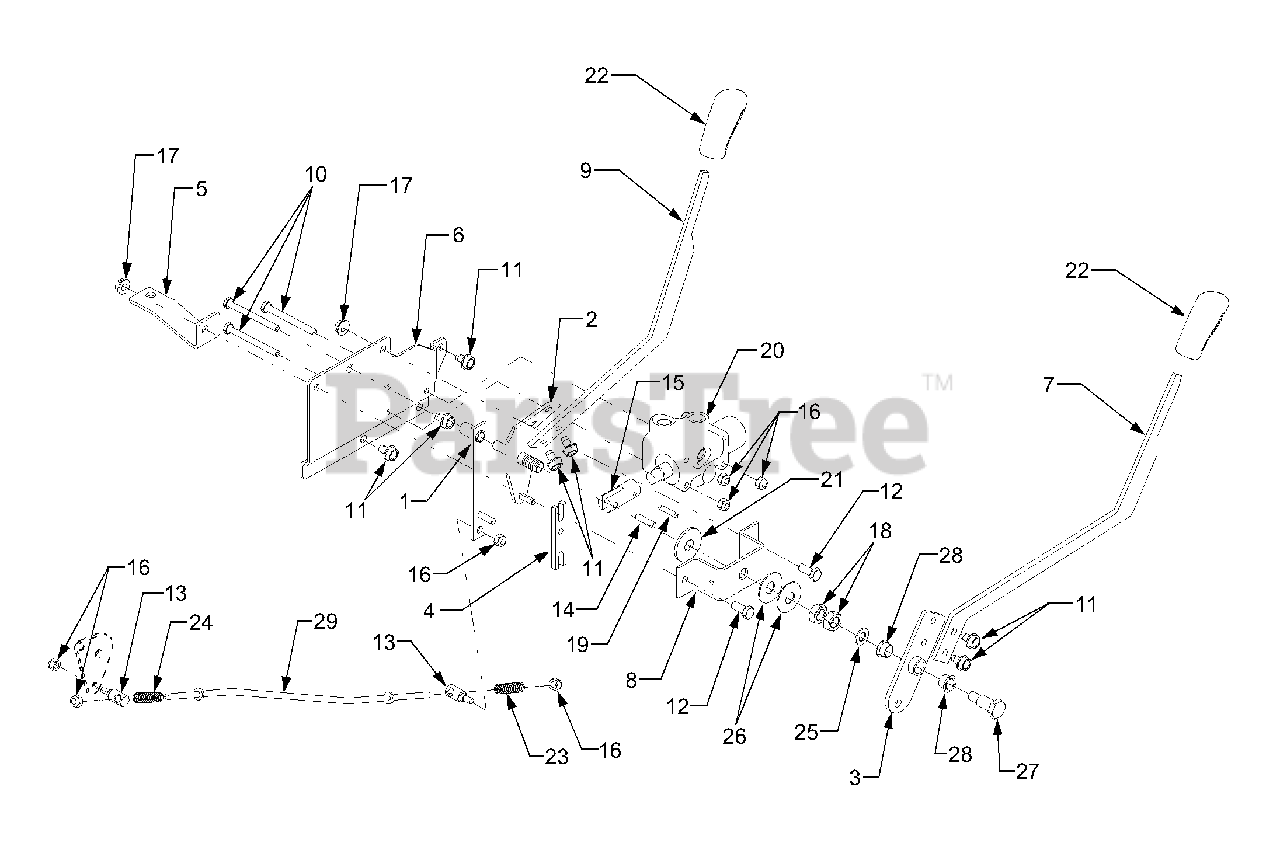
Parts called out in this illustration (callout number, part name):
1	Link Assembly, Feedback
2	Link Assembly, Input
3	Hub Assembly, HI-LO Shifter
4	Link, Feedback
5	Bracket, Lift Brace
6	Bracket, Valve Mtg
7	Handle, HI-LO Shifter
8	Bracket, Lift Mtg
9	Handle, Lift
10	Screw, Hex Cap, 1/4-20 x 2.75 GR5
11	Screw, Hex Wash Hd. Tapp 5/16-18 x .5
12	Screw, Hex Cap, 5/16-18 x .75 GR5
13	Ferrule, Feedback Adjustment
14	Pin, .25 x 1.0
15	Link, Valve
16	Nut, Hex Nylon Insert Lock 14-20 GR8
17	Nut, Hex Flange Lock, 5/16-18 GR5
18	Nut, Hex Jam, 1/2-20 GR5
19	Pin, Spirol, 3/16 x 1.0
20	Valve, Hydaulic Lift
21	Washer, Friction, .515 x 1.5 x .12
22	Grip, Handle
23	Spring, Compression
24	Spring, Compression
25	Washer, Flat, .375 x .738 x .063
26	Washer, Belleville, .53 x 1.375 x .06
27	Screw, Shoulder, .5 x .835:3/8-16
28	Bearing, Nylon Flange .5 ID
29	Rod, Feedback
